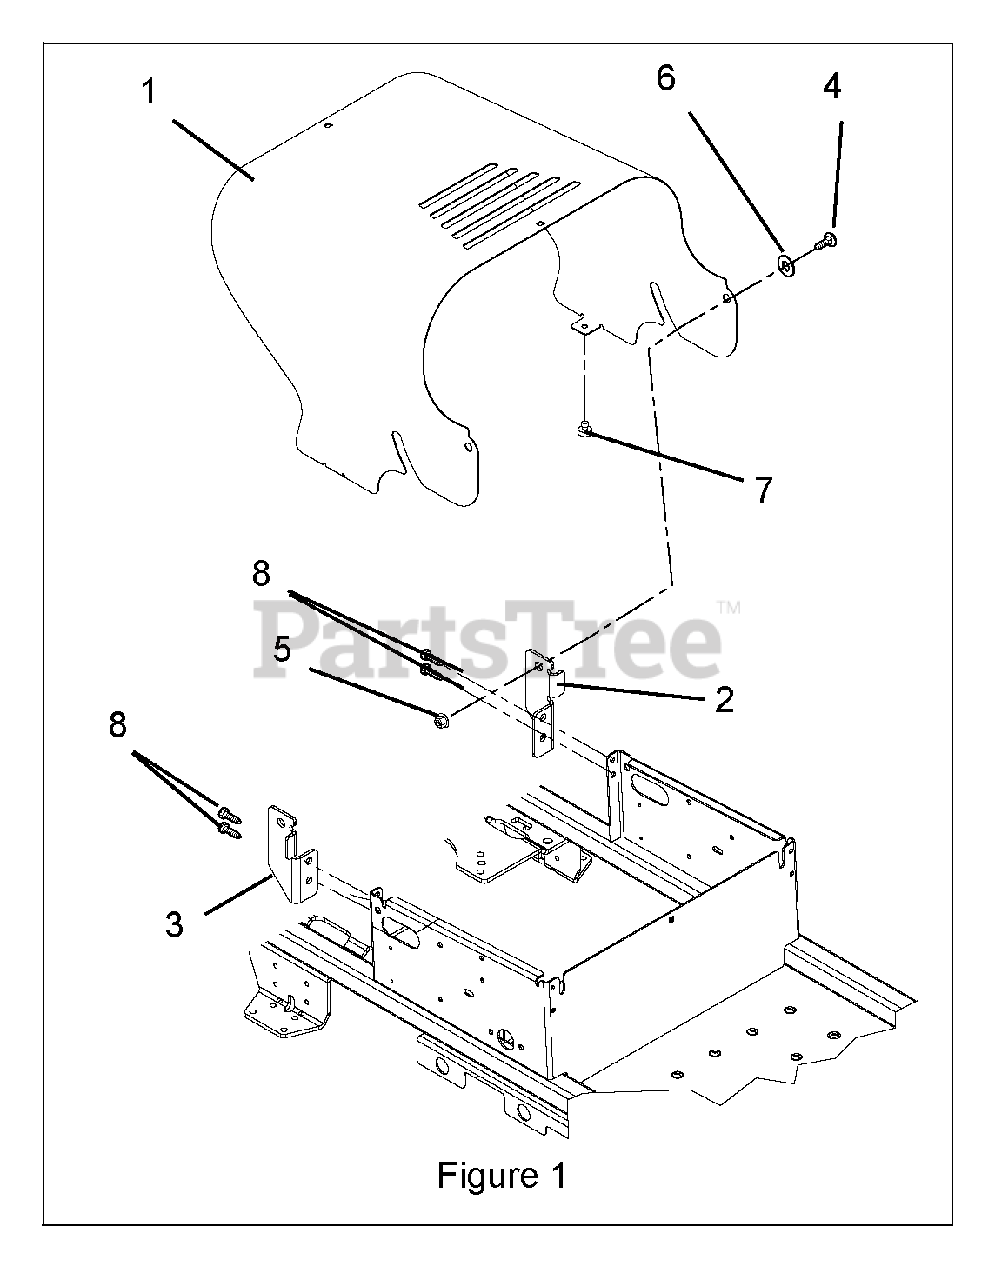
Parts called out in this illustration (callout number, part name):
2	Left Hood Mount
3	Right Hood Mount
4	3/8" x 5/32" Shoulder Bolt
5	3/8" Top Lock Flange Nut
6	1/2" Nylon Flat Washer
7	Button Bumper
8	3/8" x 3/4" Self-Tapping Screw
